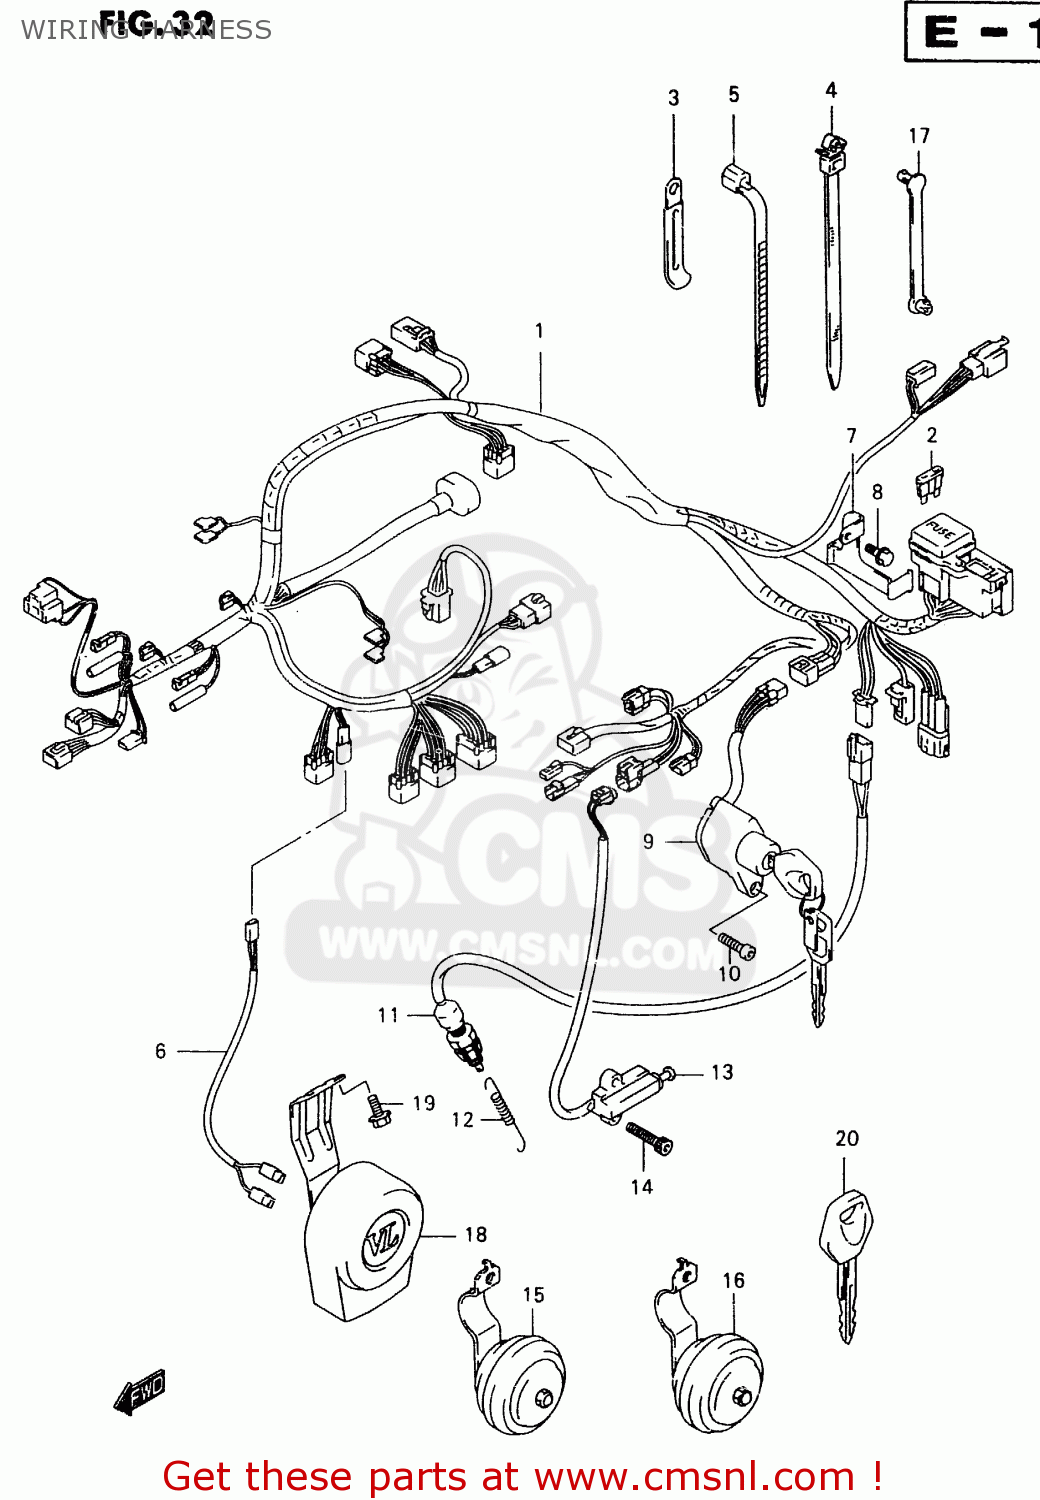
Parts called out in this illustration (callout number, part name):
1	HARNESS,WIRING
2	FUSE(10A)
3	CLAMP(L:45)
4	CLAMP(L:90)
5	CLAMP(L:125)
6	WIRE,HORN LEAD
7	BRACKET,FUSE
8	BOLT
9	SWITCH ASSY,IGNITION
10	BOLT,OIL FILLE
11	SWITCH ASSY,STOP LAMP
12	SPRING,STOP LAMP SWITCH
13	SWITCH ASSY,SIDE STAND
14	SCREW
15	HORN ASSY,R
16	HORN ASSY,L
17	CLAMP(L:33)
18	HORN ASSY
19	BOLT
20	KEY,BLANK
